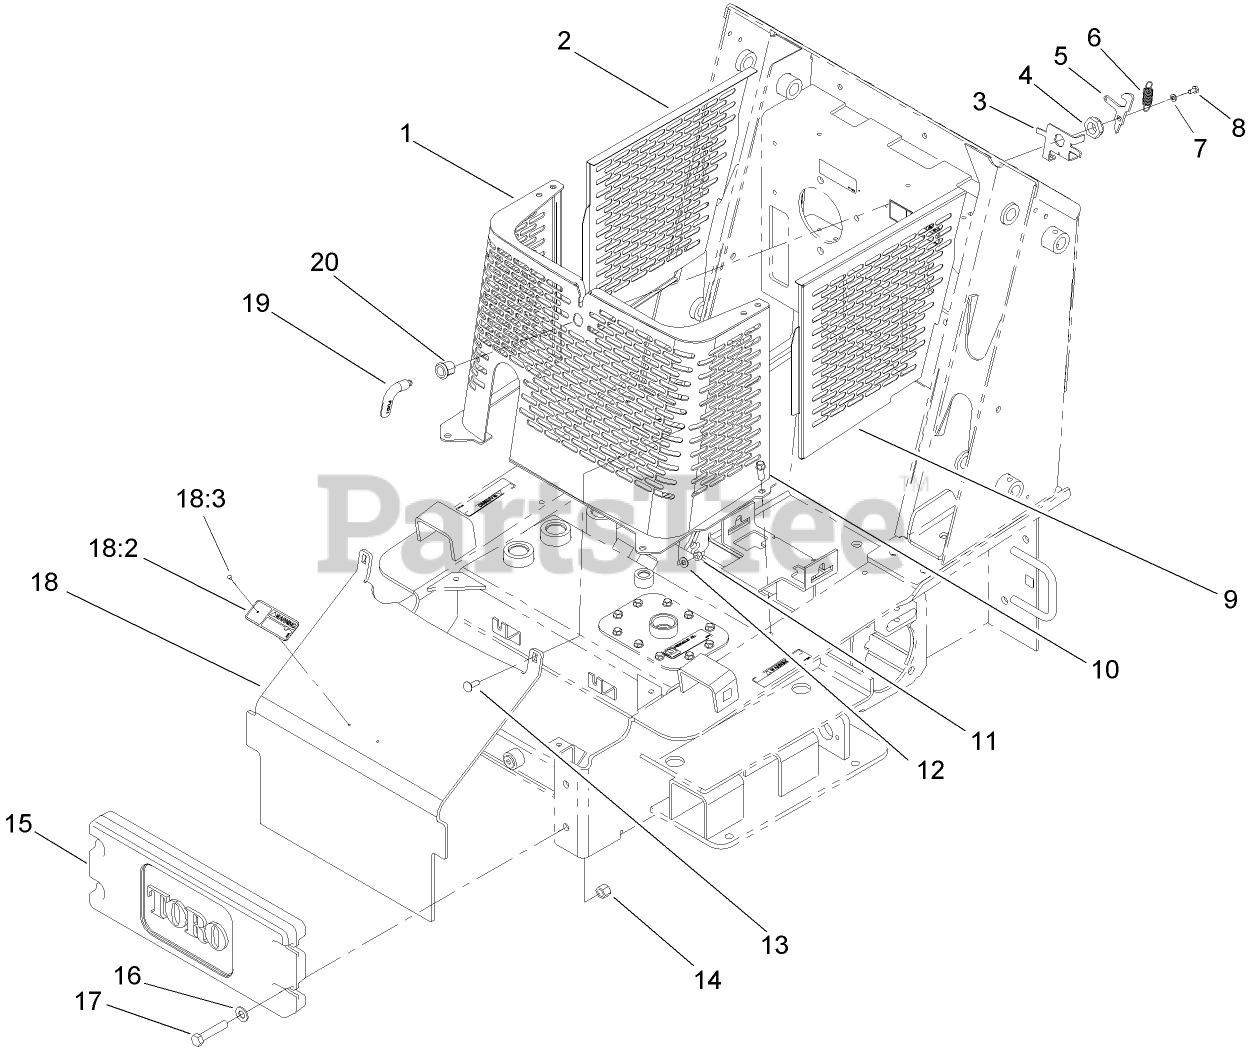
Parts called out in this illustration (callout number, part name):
1	GRILL ASM
2	PANEL-SIDE, RH
3	BRACKET-LATCH
4	NUT-LOCK, NI
5	CAM-LATCH
6	SPRING
7	WASHER-LOCK
8	SCREW-HH
9	PANEL-SIDE, LH
10	SCREW-TAPTITE
11	NUT-LOCK, NI
12	WASHER-PLAIN
13	SCREW-CARR
14	NUT-LOCK, NI
15	COUNTERWEIGHT-FRONT
16	WASHER-FLAT
17	SCREW-HH
18	HEAT SHIELD ASM
18:2	PLATE-SURFACE, HOT
18:3	RIVET-POP
19	HANDLE-LATCH
20	HOUSING-LATCH
